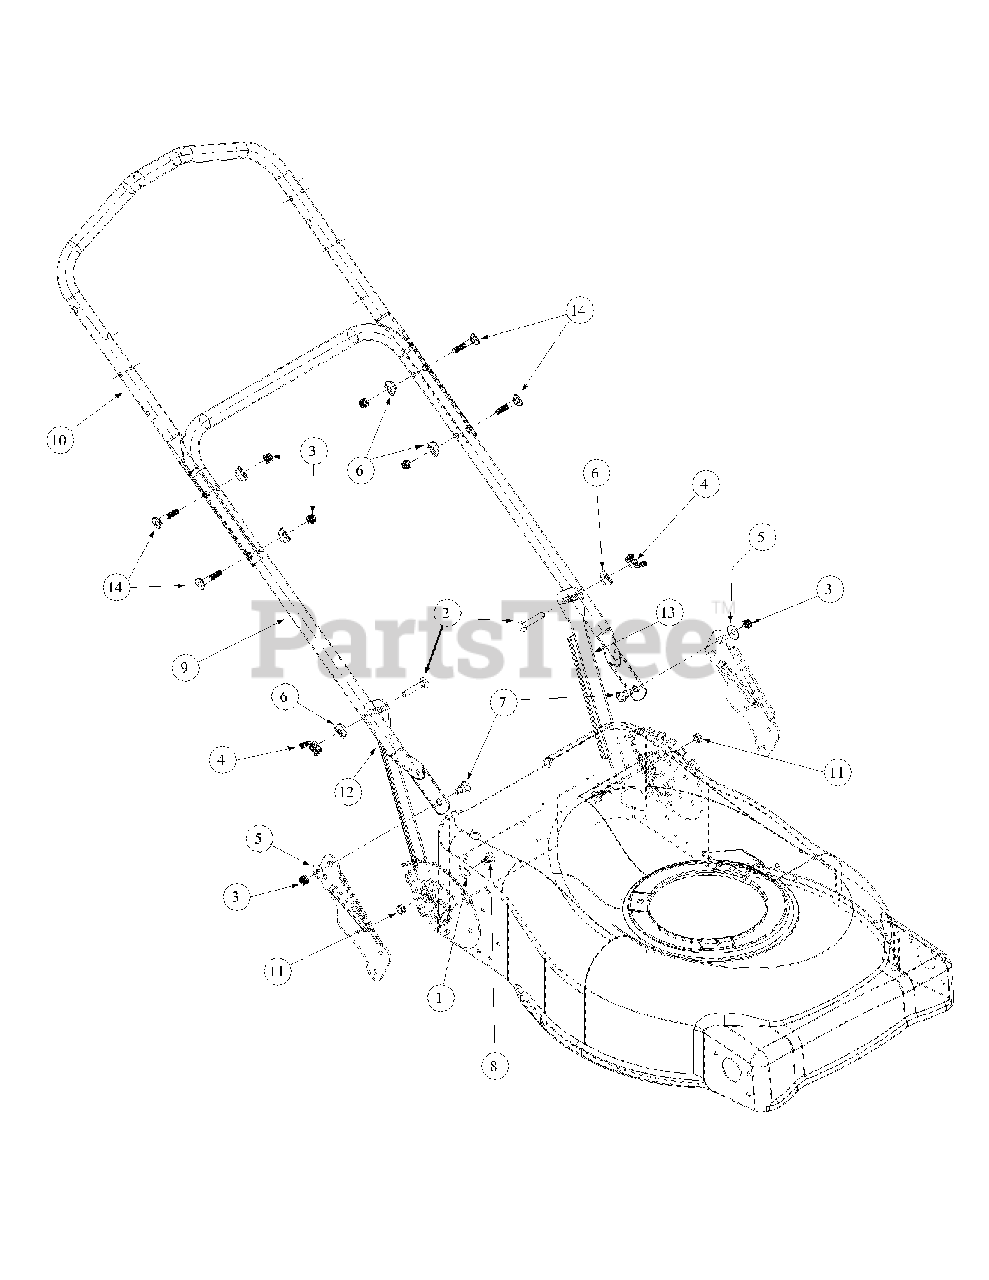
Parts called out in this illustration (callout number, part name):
1	Thrust Washer
2	Carrige Bolt, 5/16-18, 1.75
3	Hex Nut, 5/16-18, GRC, Lock
4	Wing Nut, 5/16-18, Lock
5	Belle Washer, .325 x .930 x .045
6	Saddle Washer, 320 ID X .93 OD
7	Shoulder Screw, .435 x .350, 5/16-18
8	Shield, Screw .437 x 1.62 LG
9	Lower Handle, 1.0"
10	Upper Handle, 1.0"
11	Lock Nut, 5/16-18, CEN
12	Strut, 3 Position Handle, Right hand
13	Strut, 3 Position Handle, Left hand
14	Carrige Bolt, 5/16-18 x 2.0 CRVD
